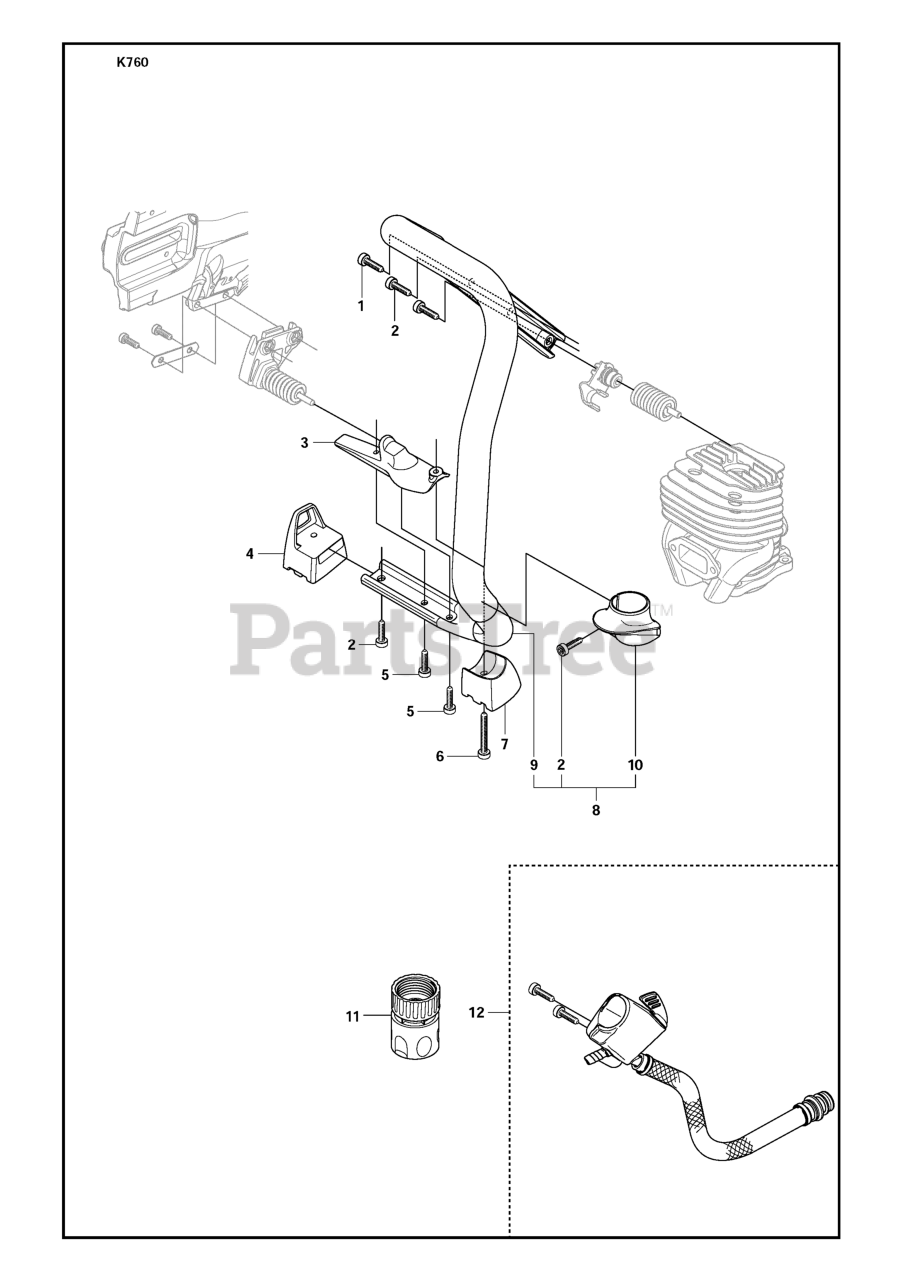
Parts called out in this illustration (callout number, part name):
3	%SPRING RETAINER
4	GROUND SUPPORT
7	GROUND SUPPORT
8	HANDLE FRONT ASSY
9	FRONT HANDLE
11	FEMALE QUICK COUPLER
11	COUPLER, 1/2" HOSE W/STOP ORIG
12	HOSE KIT, WET CUT KIT, HANDLE
